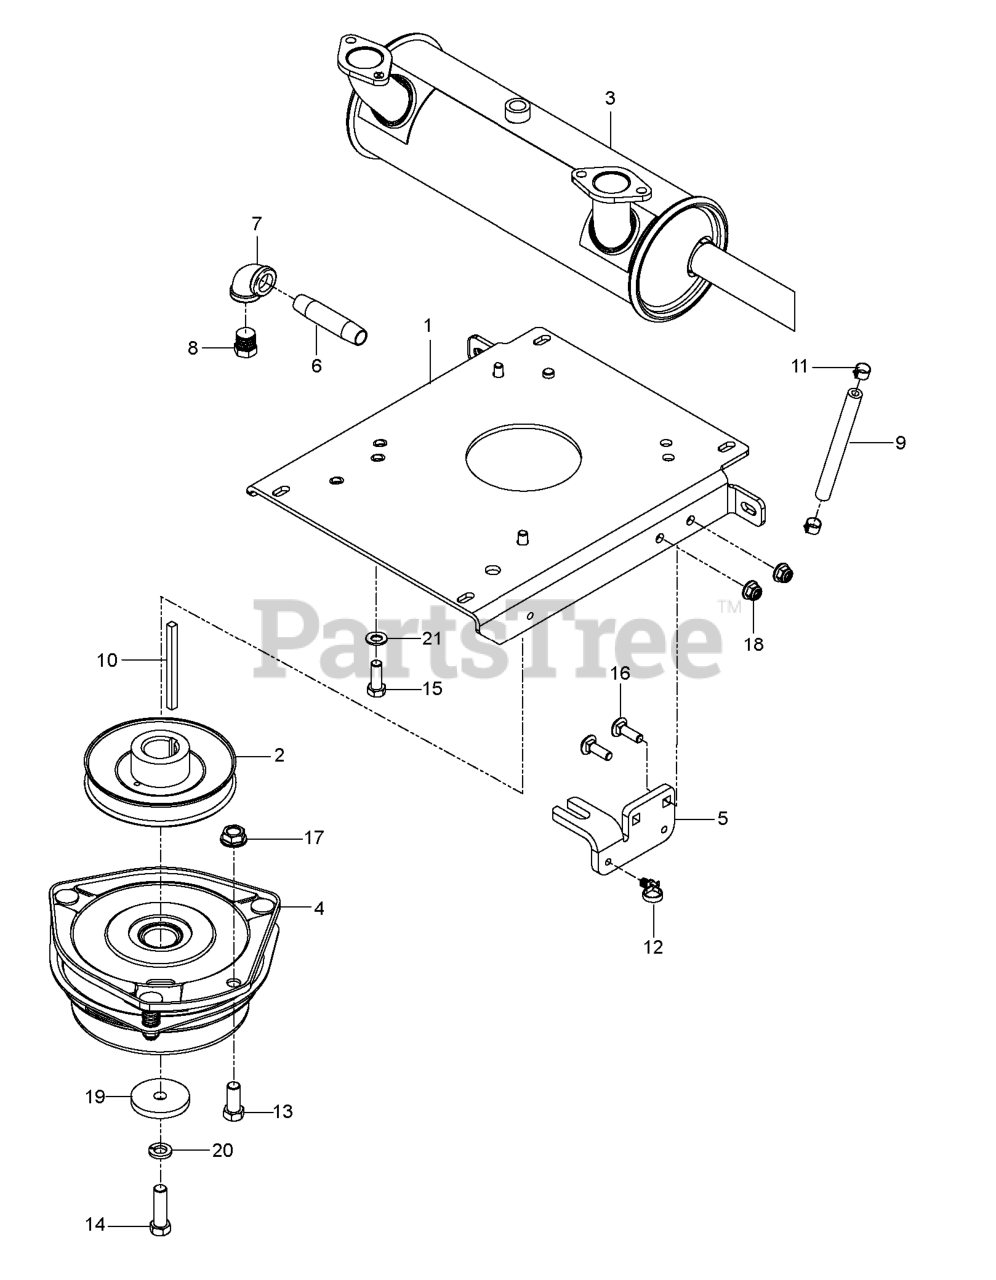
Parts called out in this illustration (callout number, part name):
1	PLATE.ENGINE.BLACK
2	PULLEY, ENGINE
3	MUFFLER.KOH.EFI.824CC
4	CLUTCH, GT3.5
5	STOP, CLUTCH, OGURA
6	PIPE NIPPLE 3/8 X 3
7	90 DEG.ELBOW 3/8NPT
8	PLUG, DRAIN 3/8 NPTF
9	FUEL LINE 5"
10	KEY, 1/4 SQ X 3.5
11	HOSE CLAMP
12	TIE WRAP, 8-3/8", W/CLIP
13	HCS 7/16-14 X 1 GR 5 ZD
14	CLUTCH BOLT7/16-20X1.5GR5.96HR
15	HCS 3/8-16X1.GRD.5.ZD
16	RHSNB 5/16C X 1
17	NUT 7/16C WHIZ
18	5/16-18 NYLOC FLANGE NUT
19	BLADE WASHER
20	WASHER 7/16 LOCK
21	WASHER, 3/8 DISC SPRING SPEC
